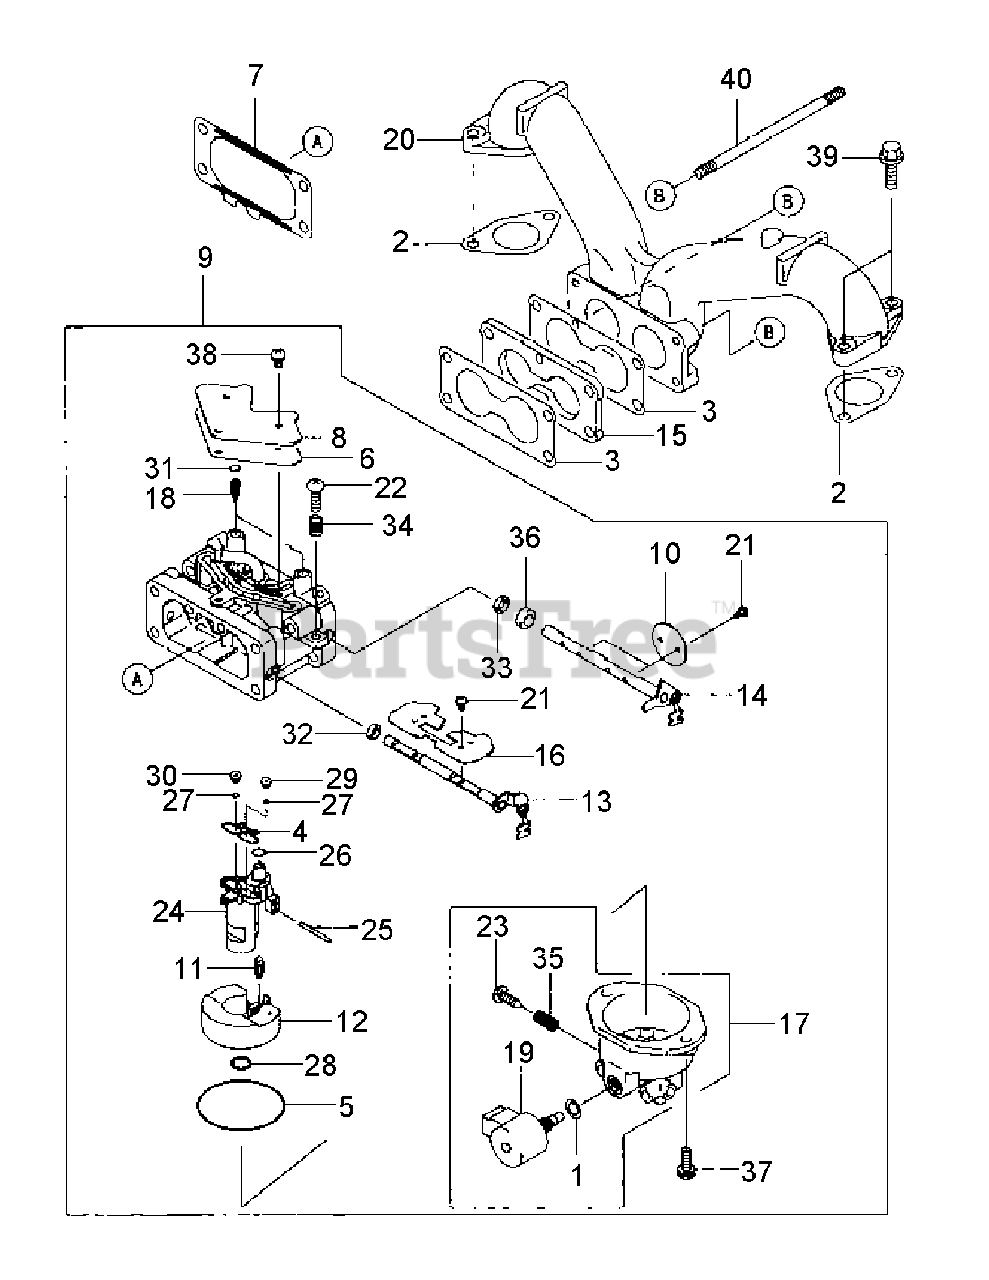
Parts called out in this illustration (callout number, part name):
2	MANIFOLD GASKET
3	CARBURETOR GASKET
4	GASKET
9	CARBURETOR ASSY.
10	THROTTLE VALVE
13	CARBURETOR SHAFT
14	CARBURETOR SHAFT
17	FLOAT CHAMBER ASSY.
20	INTAKE MANIFOLD
29	MAIN JET #104
30	MAIN JET #108
31	EXPANSION PLUG
39	FLANGED BOLT
